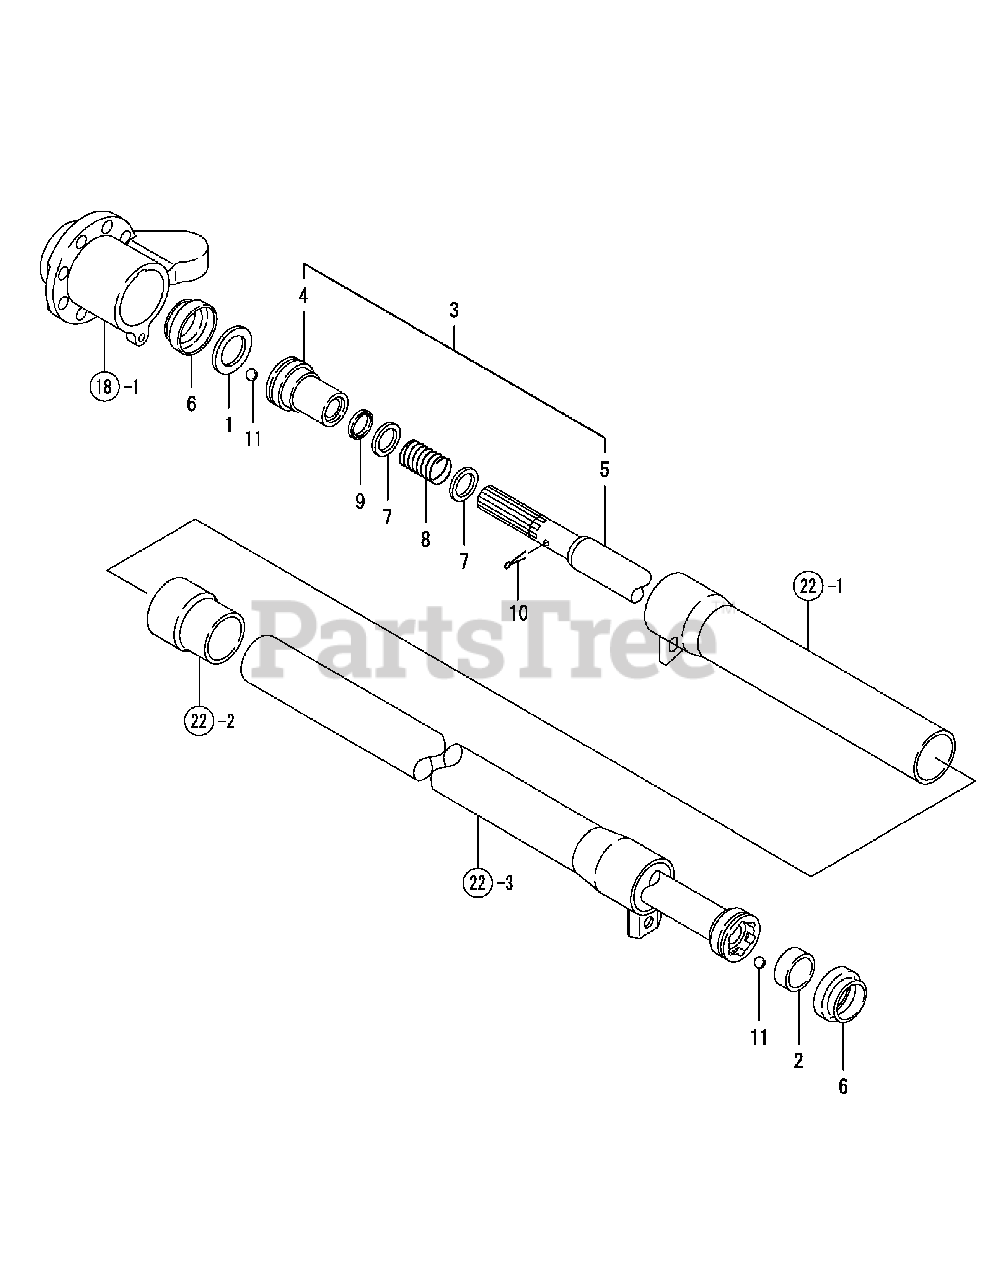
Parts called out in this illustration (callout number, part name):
1	SPACER 30X45X 2
2	SPACER 33X40X15.5
3	PROPELLER SHAFT
5	SHAFT, PROPELLER
8	SPRING,RETAINER
9	SEAL, SPLINE SHAFT
10	COTTER PIN 4.0X50
11	BALL 11/32, STEEL
